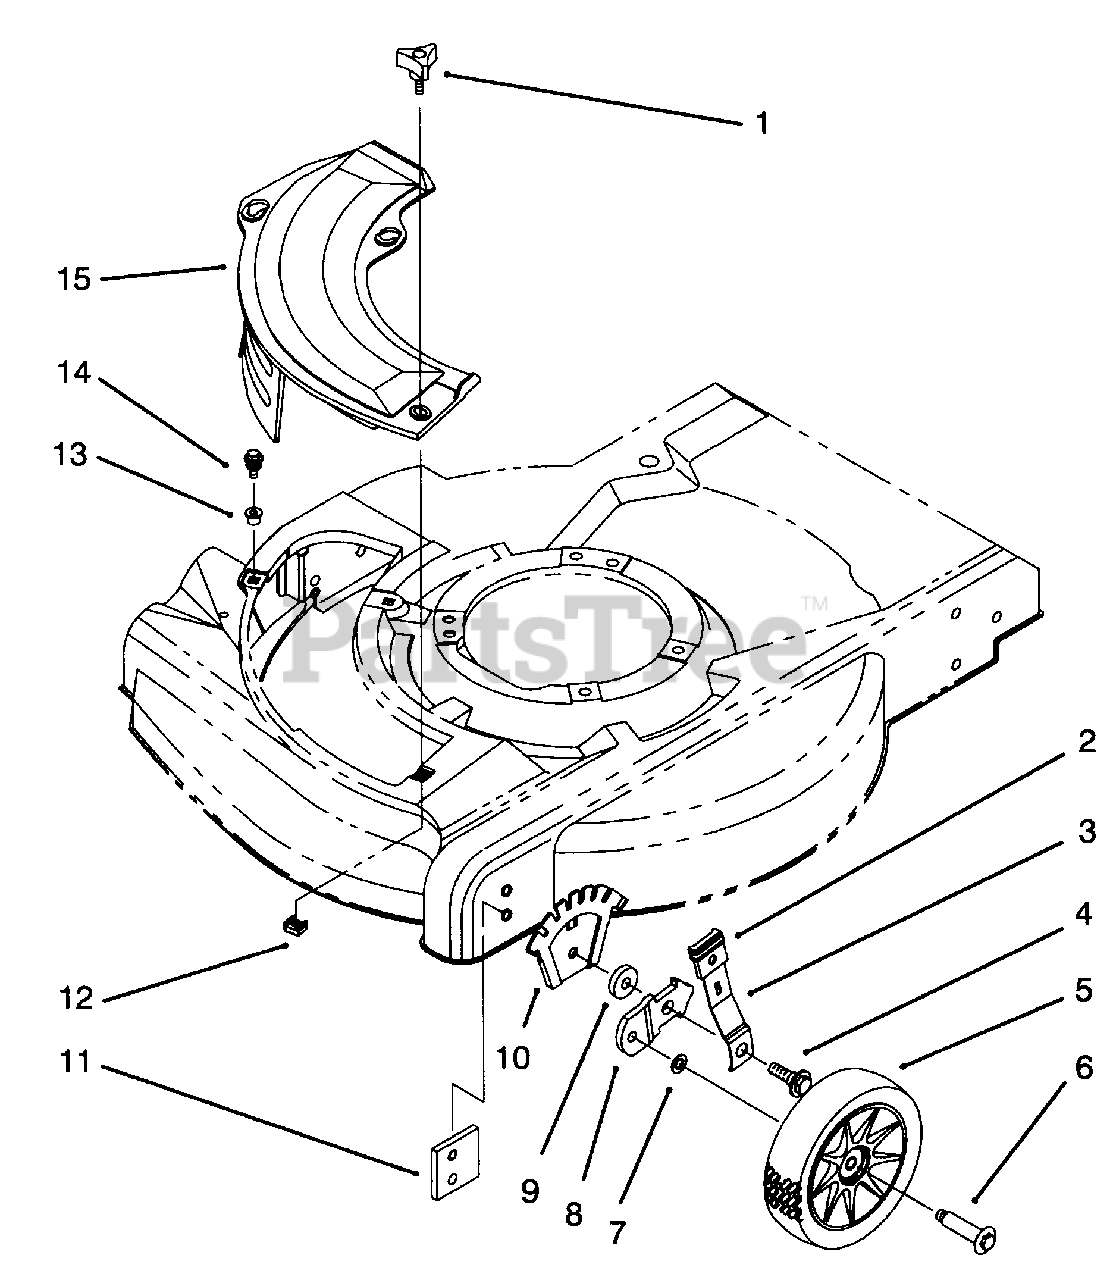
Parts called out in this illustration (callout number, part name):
1	Knob-Cover Plate
2	Knob-Height Adjust
3	Spring Arm Assembly
4	Bolt-Shoulder
5	Wheel & Tire Assembly 6"
6	Bolt-Shoulder
8	Bracket-Wheel Height Adj.
10	Plate-Height Adjust
11	Plate-Baffle
12	Nut-Cage
13	Grommet-Plastic
14	Screw-Sems Thr'd Form.
15	Plate-Mulch
